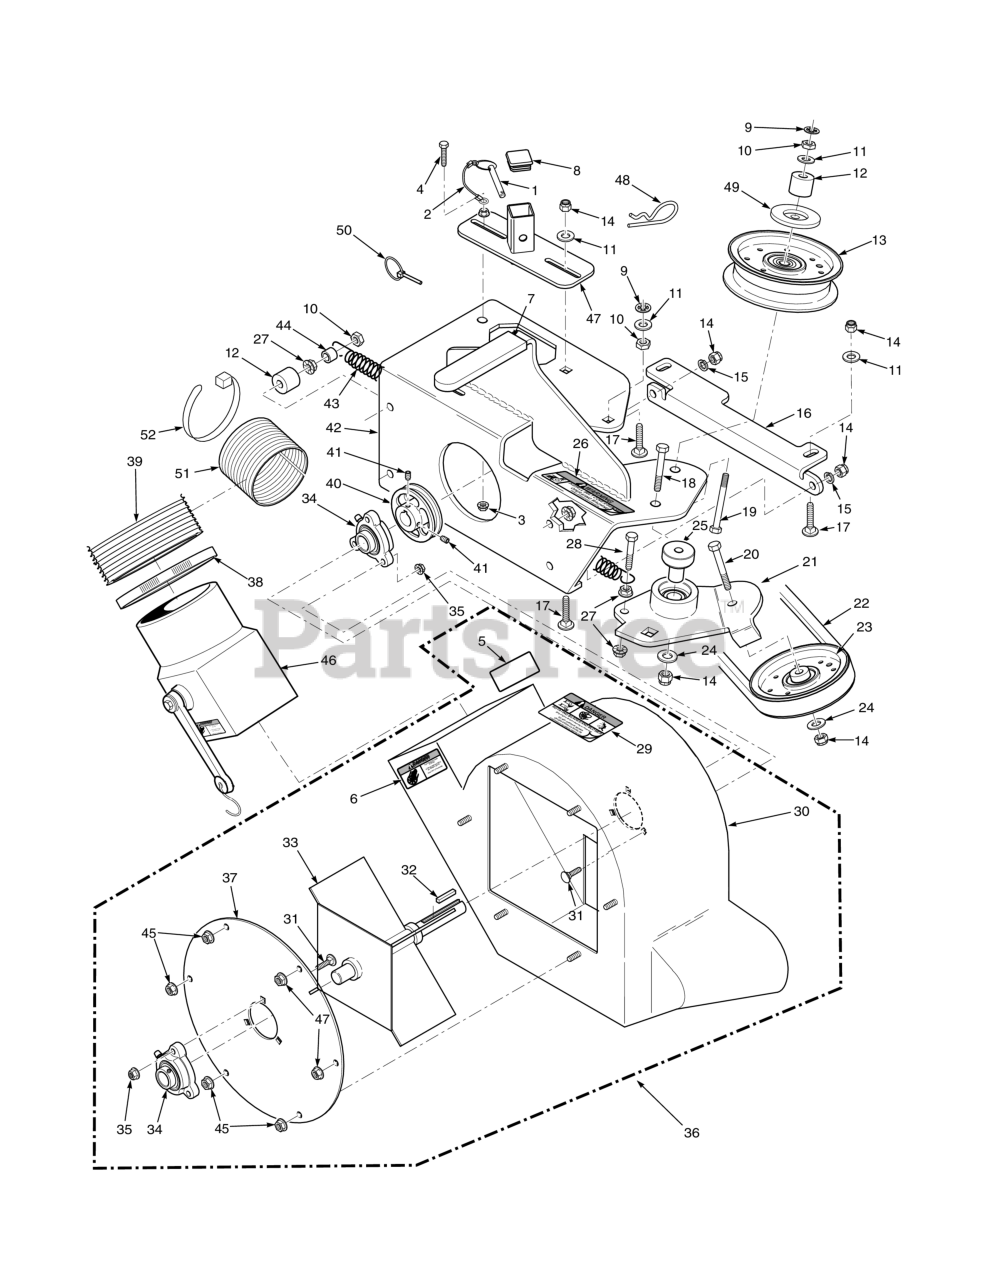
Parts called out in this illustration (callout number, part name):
1	Pin, Ring 1/2 x 2-1/4"
2	Lanyard, Deck Height Pin
3	NUT, 1/4-20 SERRATED FLANGE HEX HEAD
4	NUT, 1/4-20 SERRATED FLANGE HEX HEAD
5	Decal, Blower
6	Decal, Rotating Blower
7	Grip, Deck Latch Lever
8	Cap, Square Vinyl
9	Nut, Push-On - 3/8" Dia.
10	Bolt, Hex Head 3/8-16 x 1" Ser. Flg.
11	Flatwasher, 3/8" Special (.391 x .938 x .105)
12	SPACER, J-PULL ROD
13	Pulley, Idler 4" Dia. - 61" & 72"
14	HEX NUT, ELASTIC STOP LOCK, 3/8-16
15	Lockwasher, 3/8" Spring, Kawasaki FX / FT & FT-EFI / B&S 32BV
16	Plate, Catcher Mounting
17	Bolt, RDHD Carr. 3/8-16 x 1-1/2 (52" & 61")
18	Bolt, Hex Head 3/8-16 x 3" - 52"
19	Bolt, Hex Head 3/8-16 x 3-1/2" Full Thread
20	Bolt, Hex Head 3/8-16 x 1-3/4" (Kohler EFI)
21	Idler Arm Assembly, GC-STT 61"
22	Belt, GC-STWC 61"
23	Pulley, 3-1/2" O.D., GC-STT 52"
24	Flatwasher, 3/8 (.391 x .938 x .105 HD) Grade 8
25	Pivot, Idler - Short
26	Decal, Warning - Belt Cover
27	NUT, 3/8-16 SERRATED FLANGE HEX HEAD
28	Bolt, Hex Head 3/8-16 x 1-1/2" Grade 8 Black
29	Decal, Danger
30	Blower Housing Weldment w/Decals
31	Bolt, 5/16-18 x .75 RHSN Carriage
32	KEY 1/4 X 1/4 X 1 1/2"(FOR 1" CRANKSHAFT
33	Fan Weldment
34	Bearing Assembly
35	HEX NUT, ELASTIC STOP LOCK, 5/16-18
36	Blower Housing Assembly, GC-STT
37	COVER, BLOWER HOUSING
38	Clamp, 8-5/8" Max Dia. (61")
39	Hose, 8.00" Dia. x 53" Long
40	Pulley, 4-3/4" O.D. - 1" Bore
41	Setscrew, Hex Socket Knurl Cup Pt. 5/16 - 18 (nylock)
42	Frame, Blower Mount
43	Spring, Helper (61" Cutter Deck Only)
44	Spacer, Deck Assist
45	Nut, Serrated Flange 5/16-18 (Right Front Engine Mounting, Briggs and Kohler Only)
46	Adapter, Blower GC-STC,
47	Receiver Weldment, Mount Post - 61"
48	Hair Pin Cotter, .177" x 3-1/4"
49	Quick Pin, 5/16" Dia.
50	Quick Pin, 5/16" Dia.
51	Hose, 8" Dia. x 24" Split
52	Cable Tie, .345 X 31.5 Black
